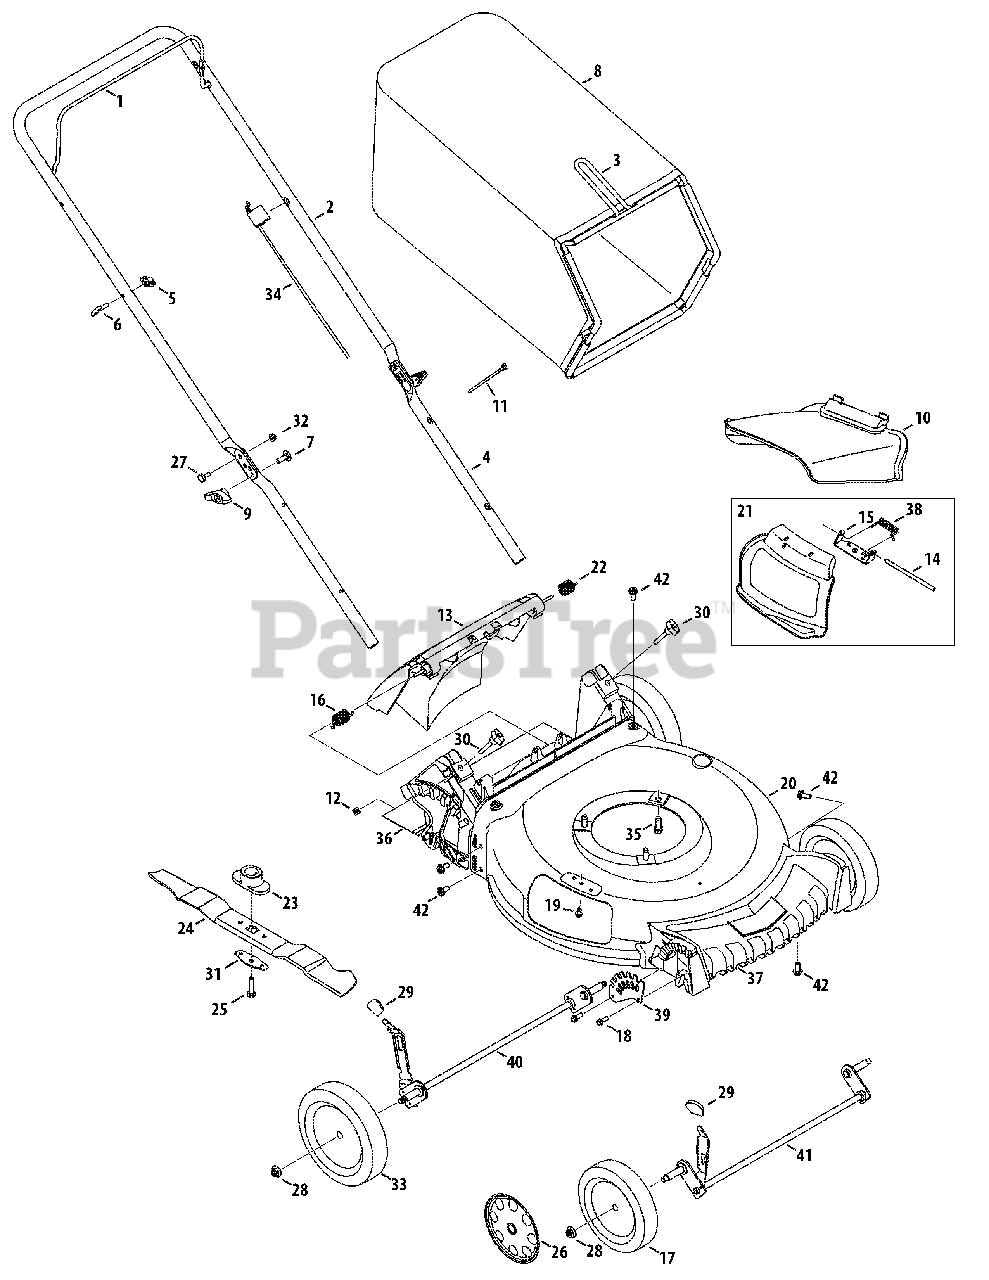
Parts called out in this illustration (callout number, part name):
1	Blade Control
2	Upper Handle
3	Grass Catcher Frame
4	Lower Handle
6	Rope Guide
7	Carriage Screw, 5/16-18
8	Grass Bag
10	Side Chute w/Flap
11	Cable Tie
12	Nut, Sq., 1/4-20
13	Rear Discharge Door & Baffle Assembly-Generic
13	Rear Discharge Door & Baffle Assembly-Lowes
14	Hinge Pin
15	Chute Deflector Bracket
16	Torsion Spring - RH
17	Front Wheel
18	Screw, 1/4-15 x .750
19	Screw, 1/4-20 x .500
20	Deck, 21"
21	Hinged Mulch Plug Assembly
22	Torsion Spring - LH
23	Blade Adapter
24	Mulching Blade
25	Screw, 3/8-24 x 1.50
27	Sldr. Screw, .375 x .126 x 1/4-20
28	Flange Lock Nut, 3/8-16
29	Adjustment Lever Knob
30	Wing Nut
31	Blade Bell Support
32	Nut, Flange Lock, 1/4-20
33	Rear Wheel
34	Control Cable
35	TT Sems Screw, 3/8-16 x 1.0
36	Trail shield
37	Front Cover
38	Torsion Spring
39	Front Height Adjuster Plate
40	Rear Axle Assembly
41	Front Axle Assembly
42	Screw, 5/16-14 x .750
